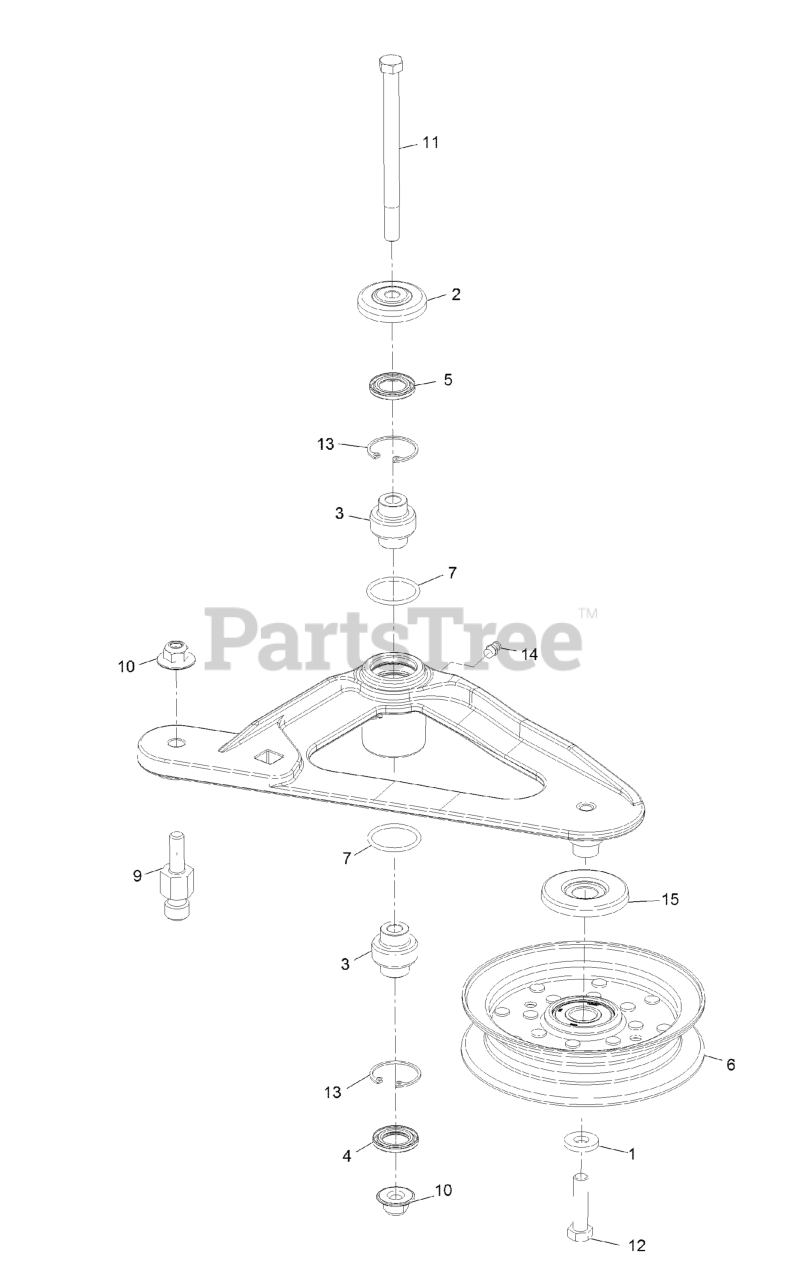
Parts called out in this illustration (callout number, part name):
2	GUARD-TOP
3	BEARING-SPHERICAL
4	SEAL-LIP, DOUBLE
5	SEAL-LIP, SINGLE
6	IDLER-PULLEY, FLAT
9	PIN-SPRING, ANCHOR
10	Nut-Nyloc 3/8-16 Flg
11	SCREW-SHOULDER, HH
12	SCREW-HH
13	RING-SNAP
14	FITTING-GREASE
15	SHIELD-GUARD, DUST
